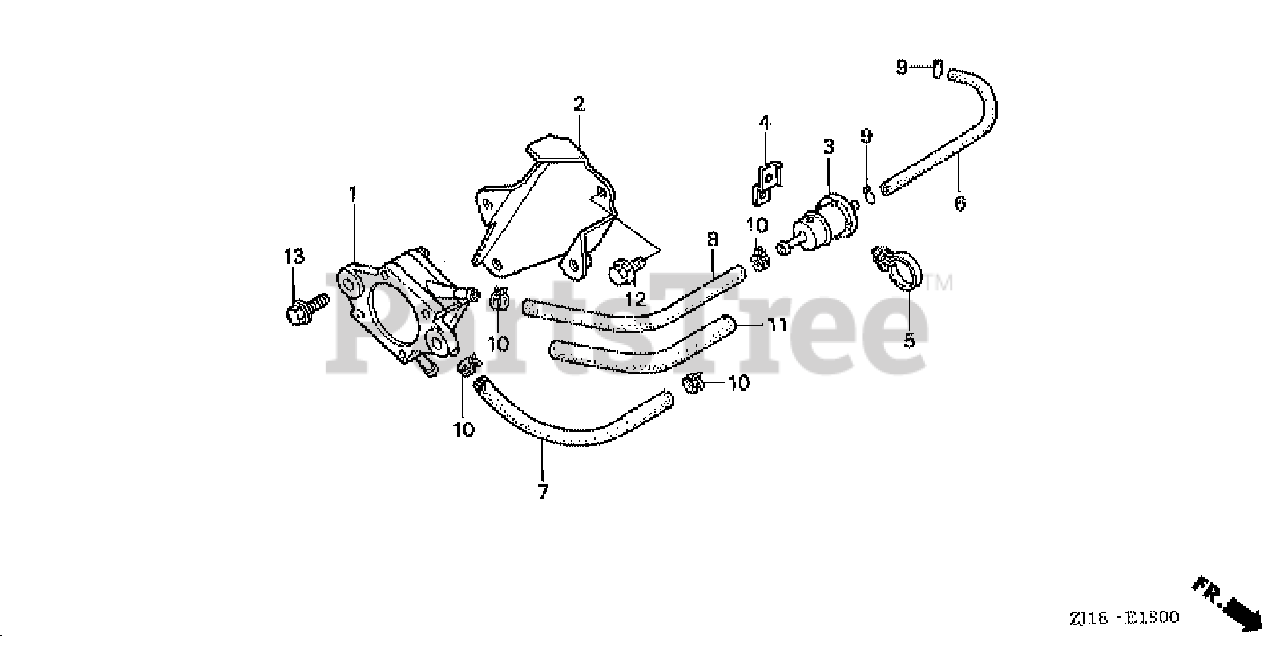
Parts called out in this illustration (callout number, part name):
1	PUMP ASSY., FUEL
2	STAY, FUEL PUMP
3	FILTER, FUEL
4	BASE, CLIP
5	CLIP, WIRE HARNESS
6	BULK HOSE, FUEL (4.5X3000) (4.5X110)
7	BULK HOSE, FUEL (5.5X8000) (5.5X195)
8	BULK HOSE, FUEL (5.5X8000) (5.5X215)
9	CLIP, TUBE (B8)
10	CLIP, TUBE (10.5MM)
11	BULK HOSE, VINYL (11X13X3000) (11X13X160)
12	BOLT, FLANGE (6X8)
13	BOLT, FLANGE (6X14)
